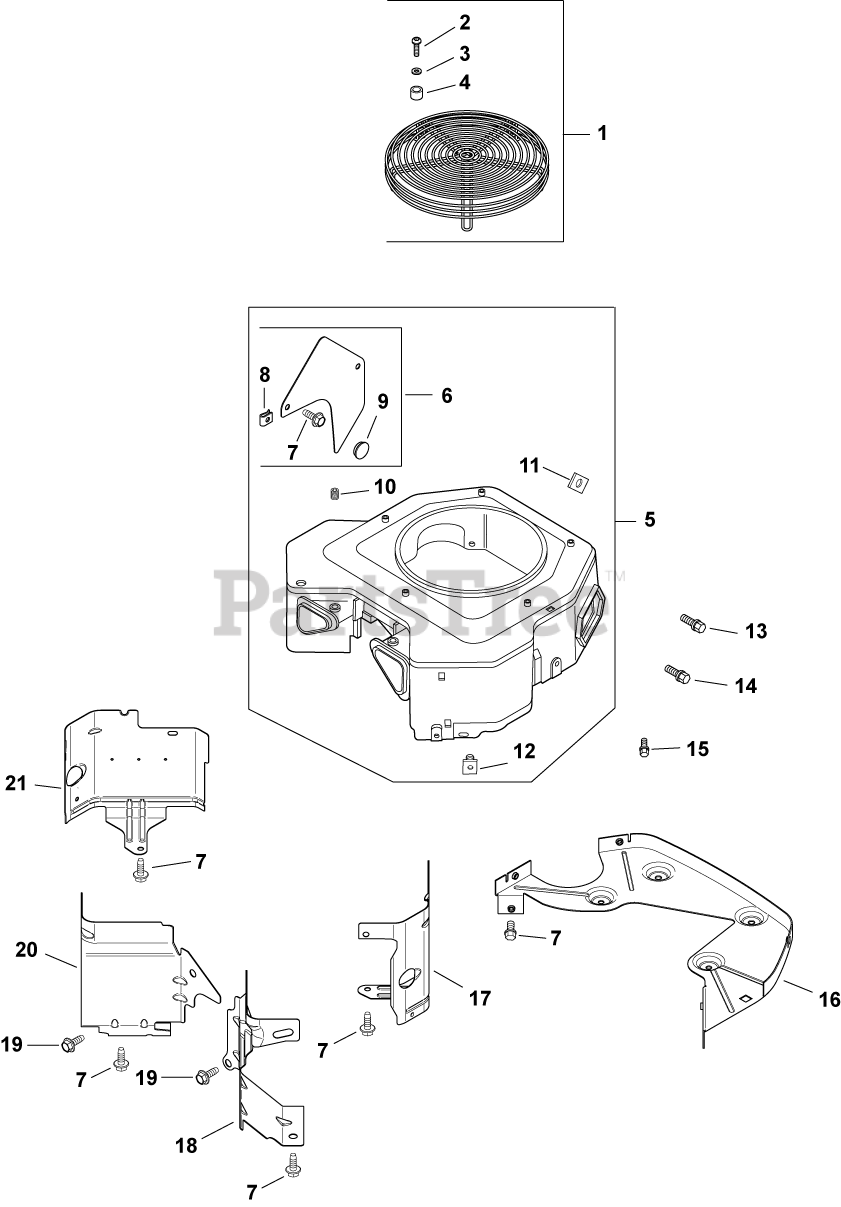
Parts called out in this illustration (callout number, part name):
1	KIT, GUARD
2	SCREW, PAN HEAD-USE 25 086 160-S
3	WASHER, FLAT 7/32"
4	SPACER USE 25 112 30-S
5	KIT, BLOWER HOUSING
6	KIT, ACCESS PANEL
7	SCREW,FLG THD FRM M6X1.0X16-(#25086397S)
8	CLIP, MOUNTING-USE 25 154 13-S
9	PLUG, BUTTON 9/16
10	SCREW, SKT SET #10-24X1/4"
11	NUT, PLASTIC (KM)-USE 25 100 37-S
12	NUT, PLASTIC
13	SCREW - USE M-545016-S
14	SCREW, FLG THD FRM M5X.8X20-(#25086399S)
15	SCREW,FLG THD FRM M5X0.8X16-(#25086398S)
16	PLATE, BACKING (OIL COOLER)-USE 24 146 5
17	BAFFLE,VALLEY #2SIDE(KM)-USE 24 063 88-S
18	BAFFLE, VALLEY #2 SIDE-USE 24 063 94-S
19	SCREW, FLG THD FRM M5X.8X10
20	BAFFLE, VALLEY (CH)-USE 24 063 93-S
21	BAFFLE, RIGHT BARREL-USE 24 063 85-S
